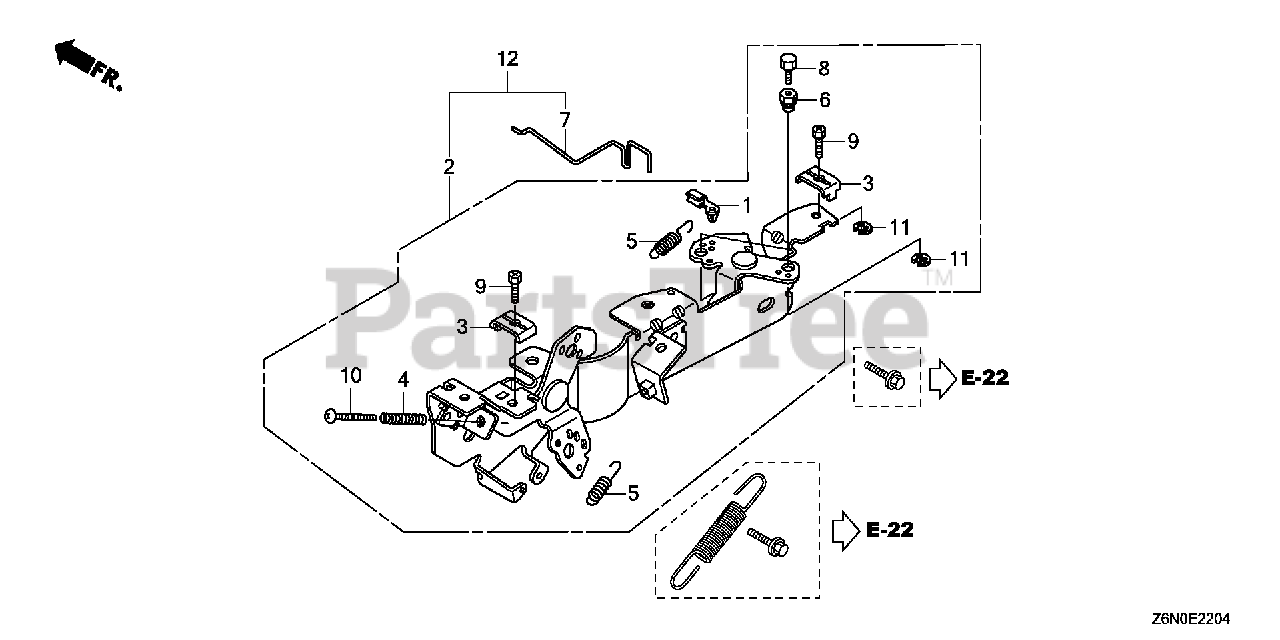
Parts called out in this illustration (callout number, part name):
1	JOINT, ROD
2	CONTROL ASSY.
3	HOLDER, CABLE
4	SPRING, CONTROL ADJUSTING
5	SPRING, CABLE RETURN
6	HOLDER, WIRE
7	ROD, CHOKE CONTROL
8	BOLT, RECESSED (4X6)
9	BOLT, RECESSED (5X16)
10	SCREW, PAN (5X40)
11	E-RING (5MM)
12	CONTROL KIT
